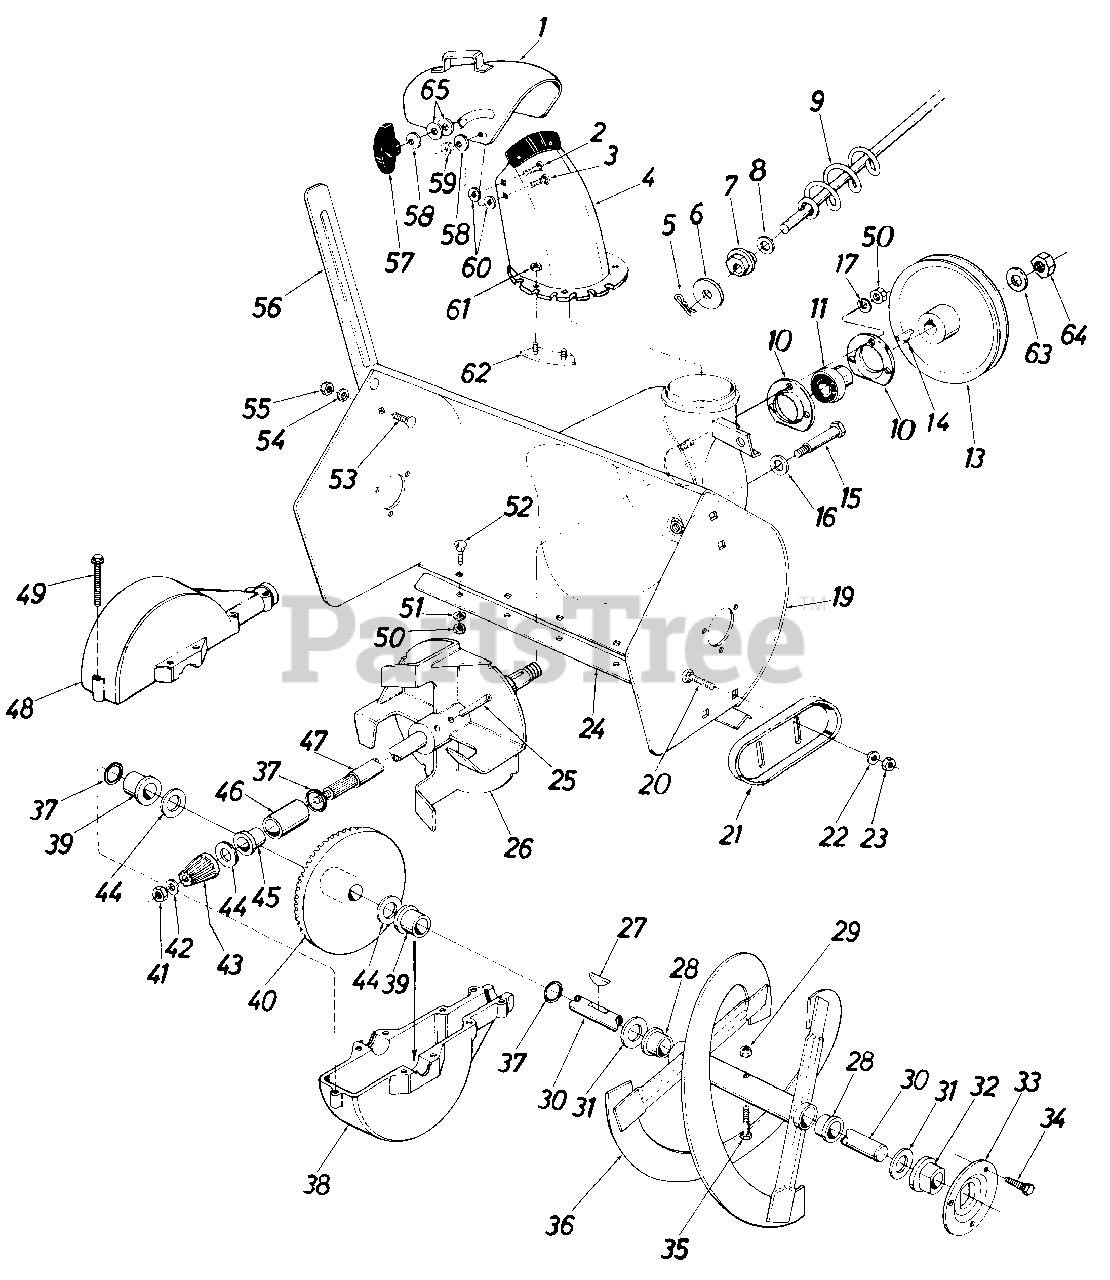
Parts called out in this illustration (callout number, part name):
1	Top Chute Ass'y.
2	Carriage Bolt 5/16-18 x 1.00" Lg.*
3	Carriage Bolt 5/16-18 x .62" Lg.*
4	Chute Ass'y.
5	Cotter Pin
6	Fl-Wash. .390 I.D. x 1.50" O.D.
7	Hex Bushing
8	Fl-Wash .385 I.D. x .62" O.D.
9	Chute Crank Ass'y.
10	Bearing Housing
11	Self-Align Brg. w/Collar.75" I.D.
13	1/2" "V"-Pulley .625" I.D. x 7.50" O.D.
14	#61 Hi-Pro Key 3116" x 5/8" Dia.
15	Shld. Bolt .50" Dia. x 2.11" Lg.
16	Bell-Wash. .40" I.D. x .88" O.D. x .06
17	L-Wash. 5/16" I.D.
19	Blower Housing Ass'y.
20	Carriage Bolt 3/8-16 x .62" Lg.*
21	Slide Shoe
22	Bell-Wash. 3/8 I.D.
23	Hex Jam Nut 3/8-16 Thd.
26	11" Dia. Blower Fan Ass'y.
27	#9 Hi-Pro Key 3/16 x 3/4" Dia.
28	Flange Brg. .75" I.D. x .88" O.D. x .62
29	Hex Ins. L-Nut 5/16-18
30	Spiral Axle
31	Fl-Wash. .75" I.D. x 1.50" O.D. x .06
32	Flange Brg. w/Flats .755" I.D.
33	Bearing Housing
34	Hex Wash. Hd. Self-Tap Scr. 5/16-24 x .50" Lg.
35	Hex Bolt 5/16-18 x 1.50" Lg.
36	Spiral Ass'y. L.H.
37	"O"-Ring 314" I.D.
38	Bevel Gear Housing Lower Half
39	Plastic Flange Brg. .755" I.D.
40	Bevel Gear
41	Hex Cent. L-Nut 5/16-24 Thd.
42	Fl-Wash. .34" I.D. x .62" O.D. x .06
43	Pinion Gear
44	Fl-Wash. .75" I.D. x 1.25" O.D. x .06
45	Flange Brg. .755" I.D.
46	Sleeve Brg. .755" I.D.
47	Blower Axle
48	Bevel Gear Housing Upper Half
49	Hex Wash. Hd. Self-Tap Scr. 1/4-20 x 1.00" Lg.
50	Hex Nut 5/16-18 Thd.
51	Bell-Wash. .34" I.D. x .88" O.D.
52	Carriage Bolt 5/16-18 x .62" Lg.
53	Carriage Bolt 5/16-18 x .62" Lg.*
54	L-Wash. 5.16" I.D.
55	Hex Nut 5/16-18 Thd.
56	Drift Cutter Bar
57	Knob
58	Bell-Wash. .34" I.D. x .88" O.D.
59	Hex Cent. L-Nut 5/16-18 Thd.
60	Fl-Wash. .53" I.D. x 1.25" O.D. x .100
61	Hex Cent. L-Nut 1/4-20 Thd.
62	Chute Flange Keeper Ass'y.
63	Fl-Wash. .64" I.D. x .94" O.D. x .06
64	Hex Jam Nut 5/8-18 Thd.
65	Fl-Wash. .344 I.D. x 1.125 O.D.
